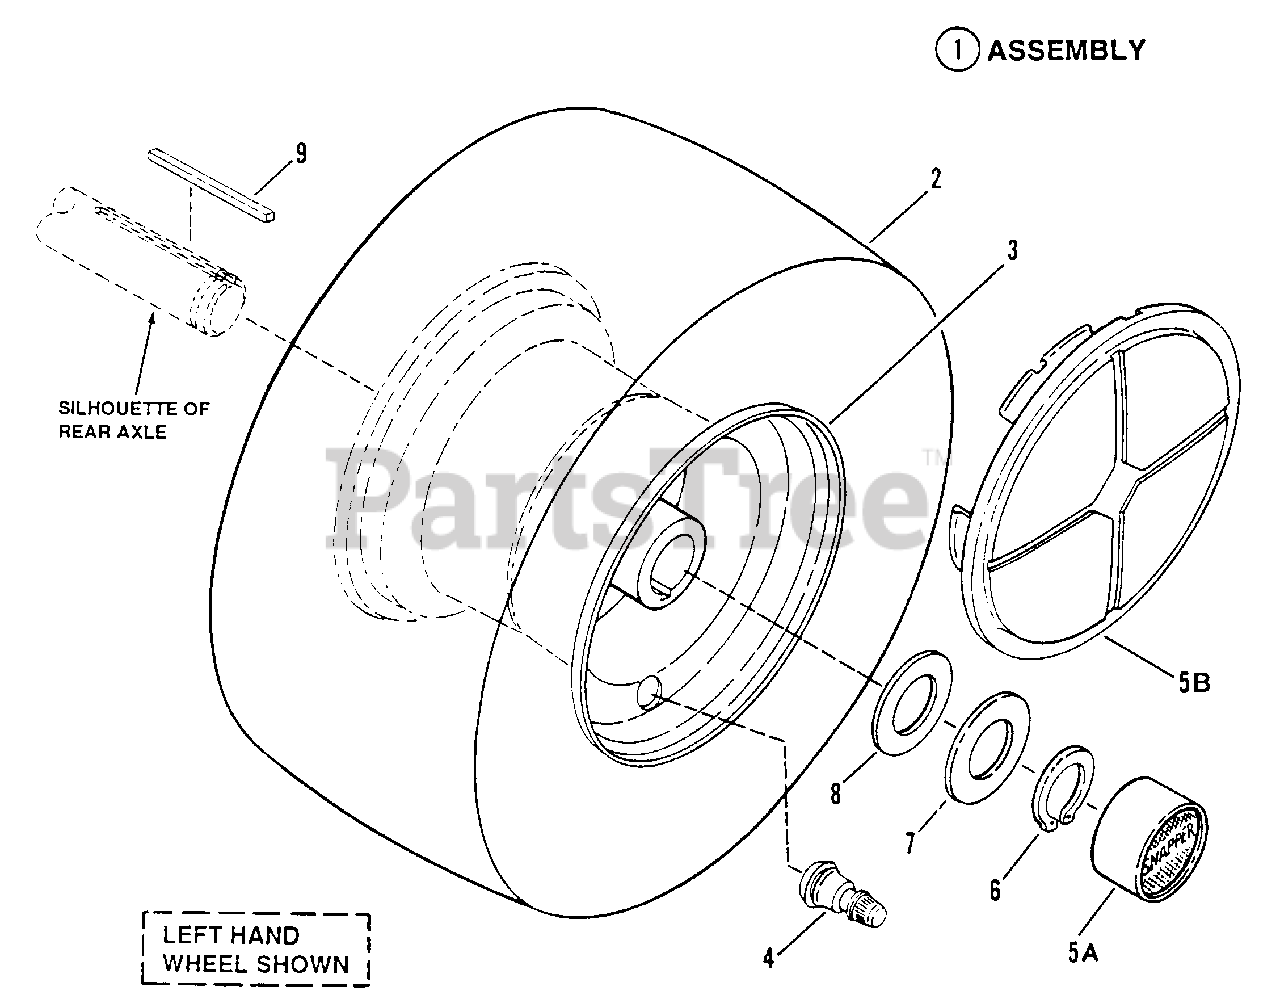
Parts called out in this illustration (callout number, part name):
1	ASSEMBLY, Rear Tire & Rim
2	TIRE, 18 x 7.50
2	TIRE, 18 x 8.50
3	RIM, 8.00 x 5.375
3	RIM, 8.00 x 7.00
4	VALVE, Air (Snap-in)
5A	HUB-CAP
5B	WHEEL-COVER
6	RING, Retaining
7	WASHER, 49/64 I.D. x 1-5/8" O.D. Thrust
8	WASHER, Flat, 49/64" I.D. x 1 1/2" O.D.
9	KEY, Square, 3/16 x 2 1/2"
